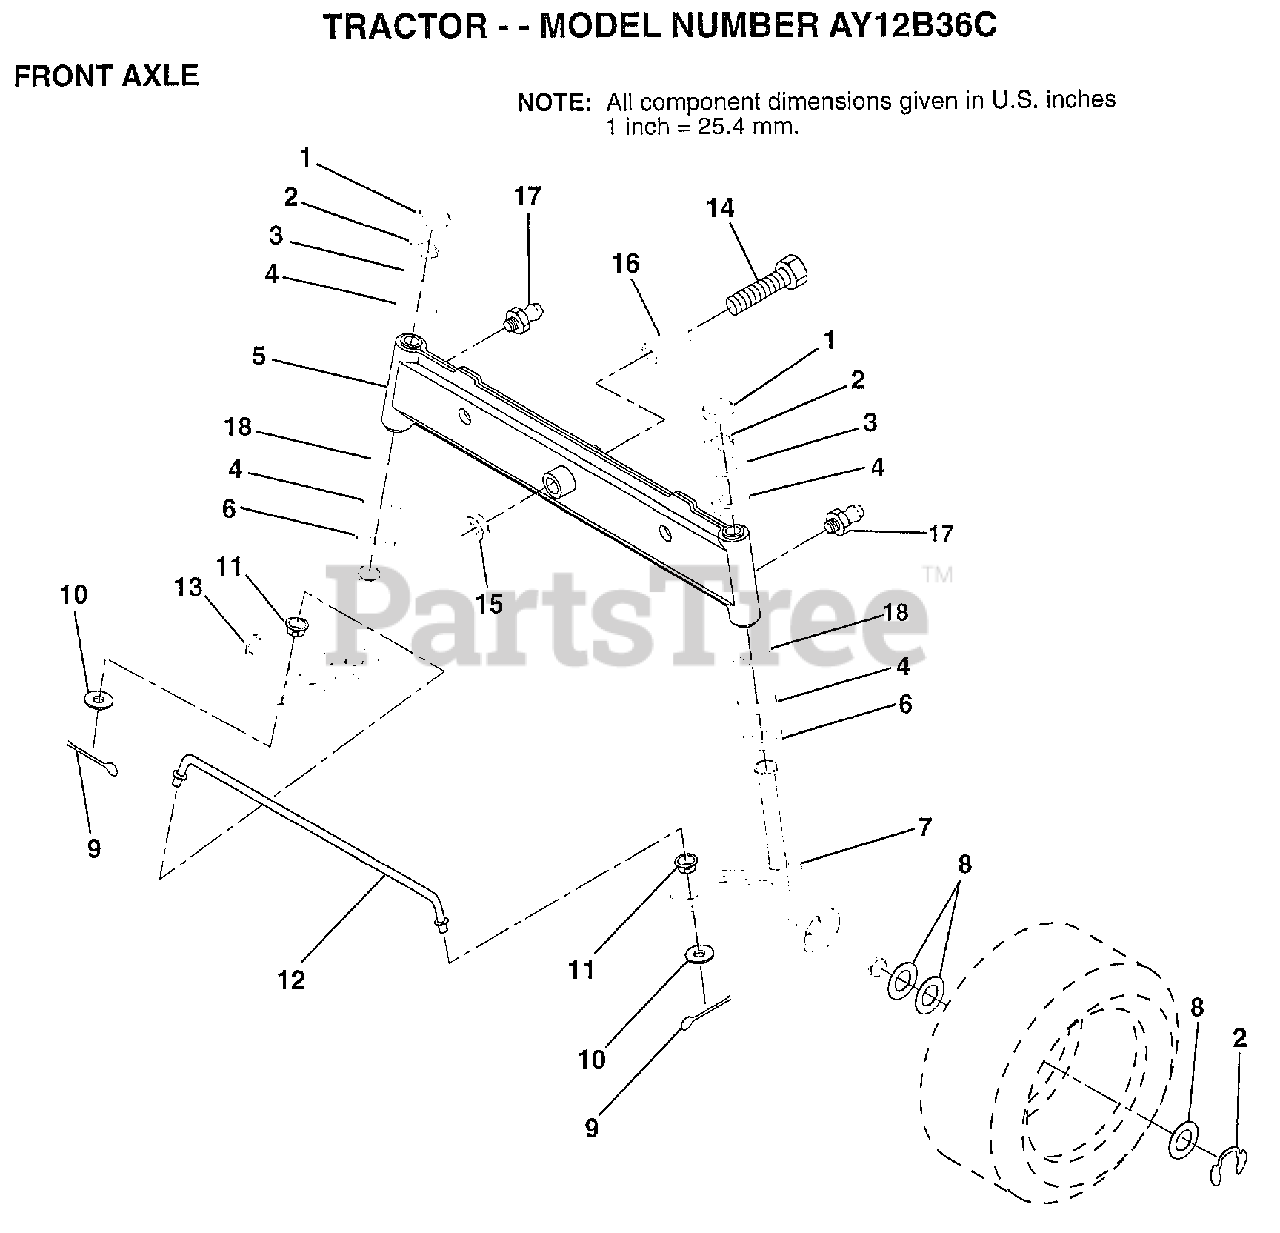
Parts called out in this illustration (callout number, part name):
1	CAP
2	RING
3	WASHER
4	COL. SRTG. BEAR.
5	AXLE ASM FRONT
6	WASHER .T
7	SPINDLE.ASSY.RH
8	WASHER
9	COTTER PIN
10	WASHER
11	BUSHING.DRAGLINK
12	TIE ROD
13	SPINDLE.ASSY.LH
14	BOLT HEX 5/8-11
15	"NUT-LOC,FLANGE LT"
16	BEARING
17	ZERK M
18	WASHER
